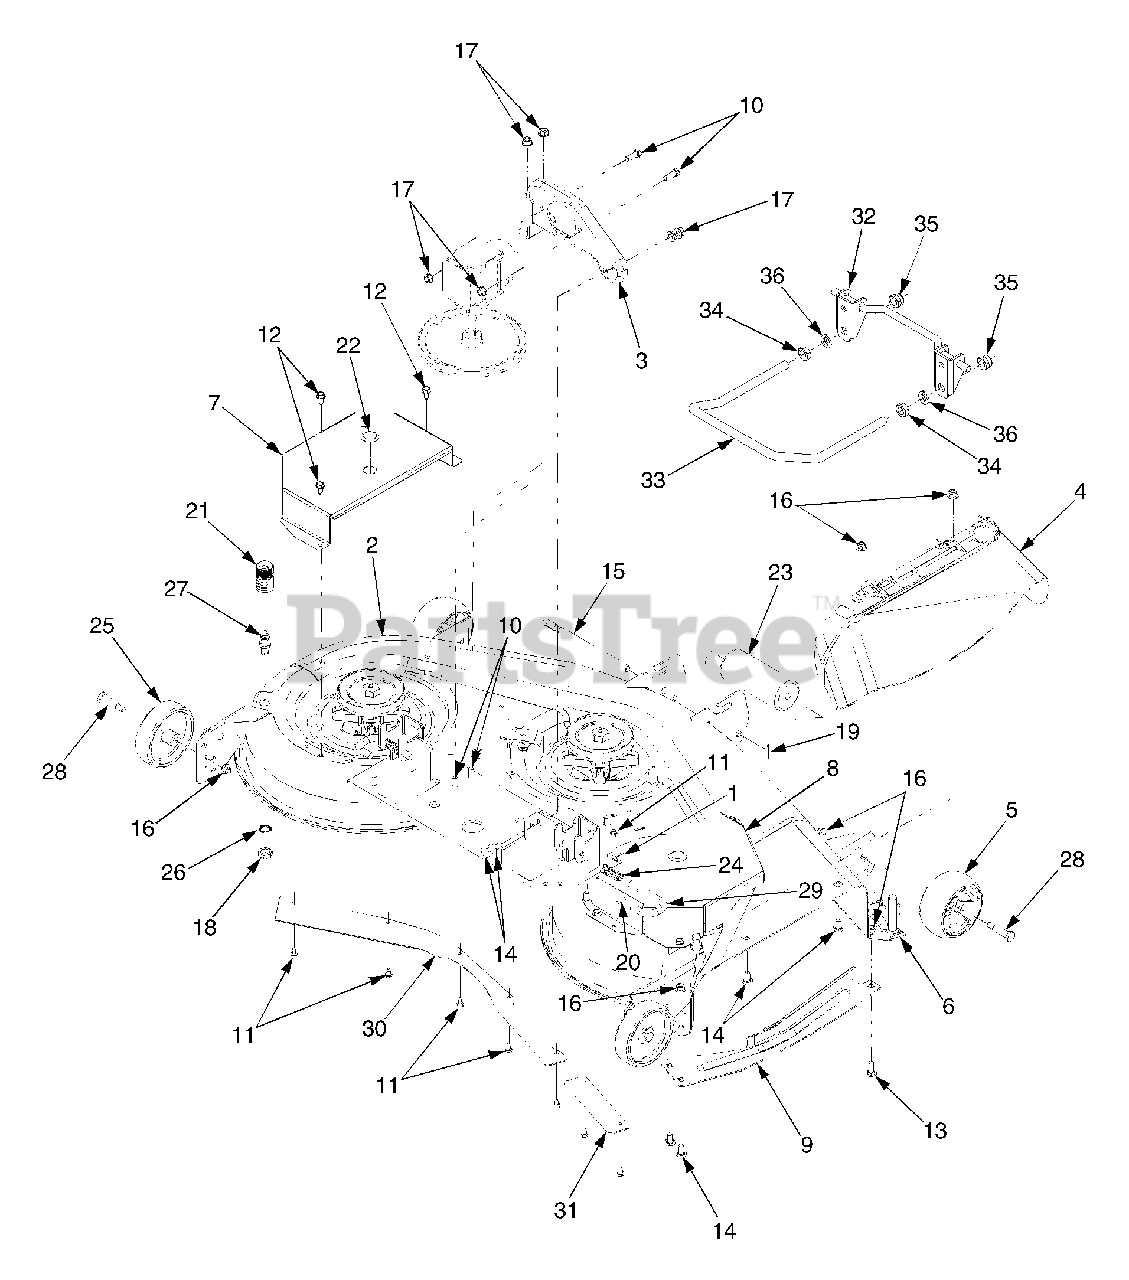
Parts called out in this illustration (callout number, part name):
1	Bracket, Hook Retainer
3	Bracket, Drive Mounting
4	Chute Assembly
5	Wheel Assembly
6	Bracket, Chute Stop
7	Shield, Spindle LH
8	Shield, Spindle RH
9	Guard, Finger
10	Screw, Hex Cap, 3/8-16 x 1.0 GR5
11	Screw, Hex Wash. Hd Tapp 1/4-20 x .5
12	Screw, Hex Wash. Hd Tapp 5/16-12 x .75
13	Bolt, Carriage, 3/8-16 x 1.0
14	Bolt, Carriage, 3/8-16 x .75
15	Pin, Roller
16	Nut, Hex Insert Lock, 3/8-16 GRF
17	Nut, Hex Flange Lock, 3/8-16 GRF
18	Nut, Hex, M16-1.5
19	Pin Cotter, 3/32 x 1.25
20	Pin, Spirol, 3/16 x 3/4
21	Adapter, Water Nozzle
22	Plug, Button
23	Roller, Front
24	Spring, Compression
25	Wheel, Deck
26	Washer, Lock
27	Nozzle, Deck Water
28	Screw, Shoulder, .498 x 1.53:3/8-16
29	Pin, Mower Support
30	Skirt, Center
32	Bracket, Front Lift
33	Rod, Front Lift
34	Nut, Hex Jam 5/8-11
35	Nut, Hex Lock 5/8-11
36	Washer, Lock 5/8" I.D.
